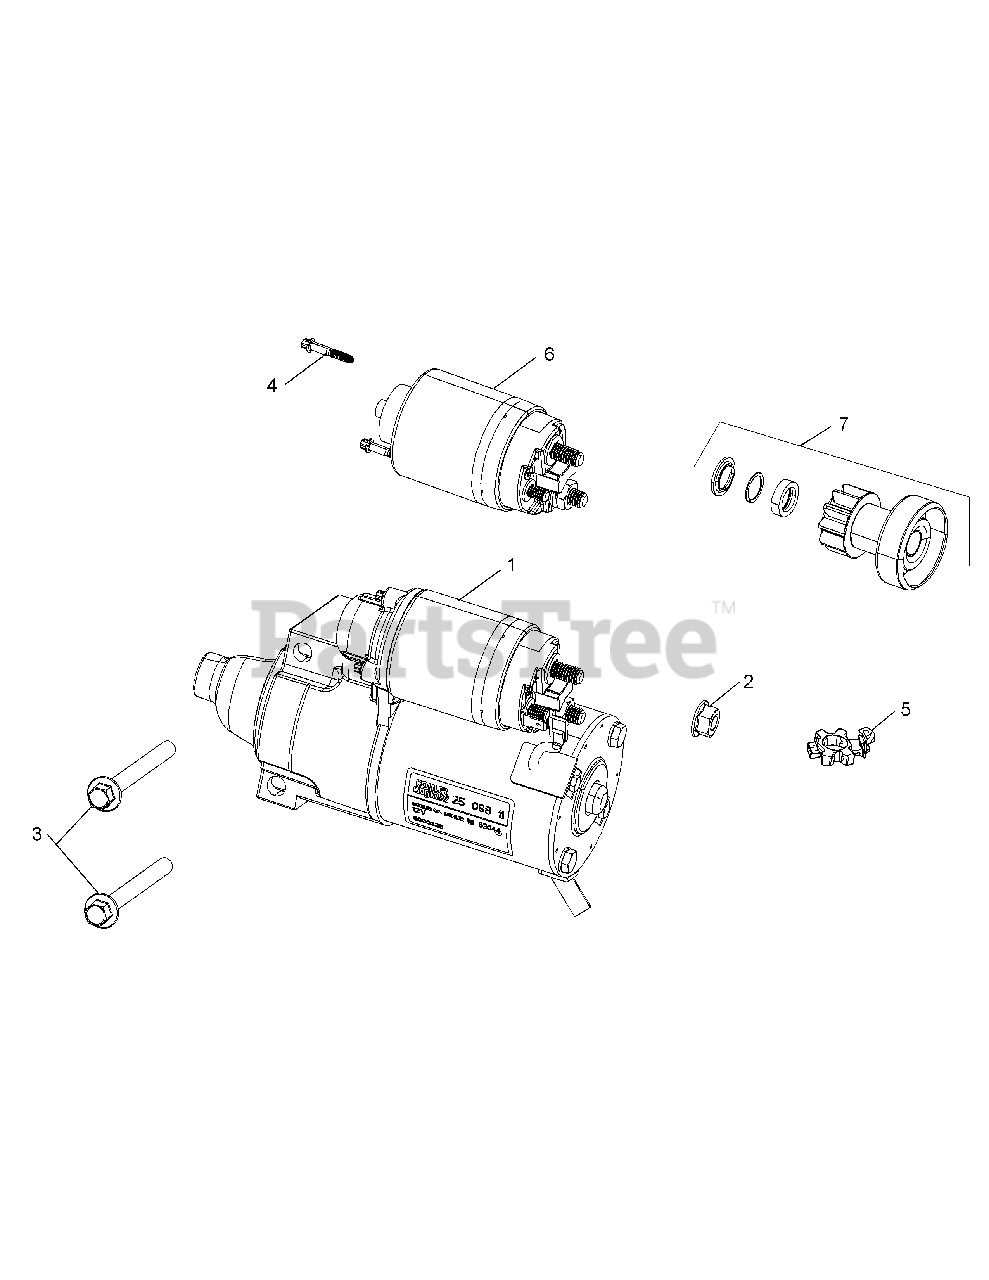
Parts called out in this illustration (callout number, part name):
1	Solenoid Shift Starter Assembly
2	Flange Nut, M8x1.25
3	Flange Screw, M8 x 1.25 x 80
4	Torx Head Screw
5	Brush Holder Kit
6	Solenoid Kit (Inc. 4)
7	Starter Pinion Kit
